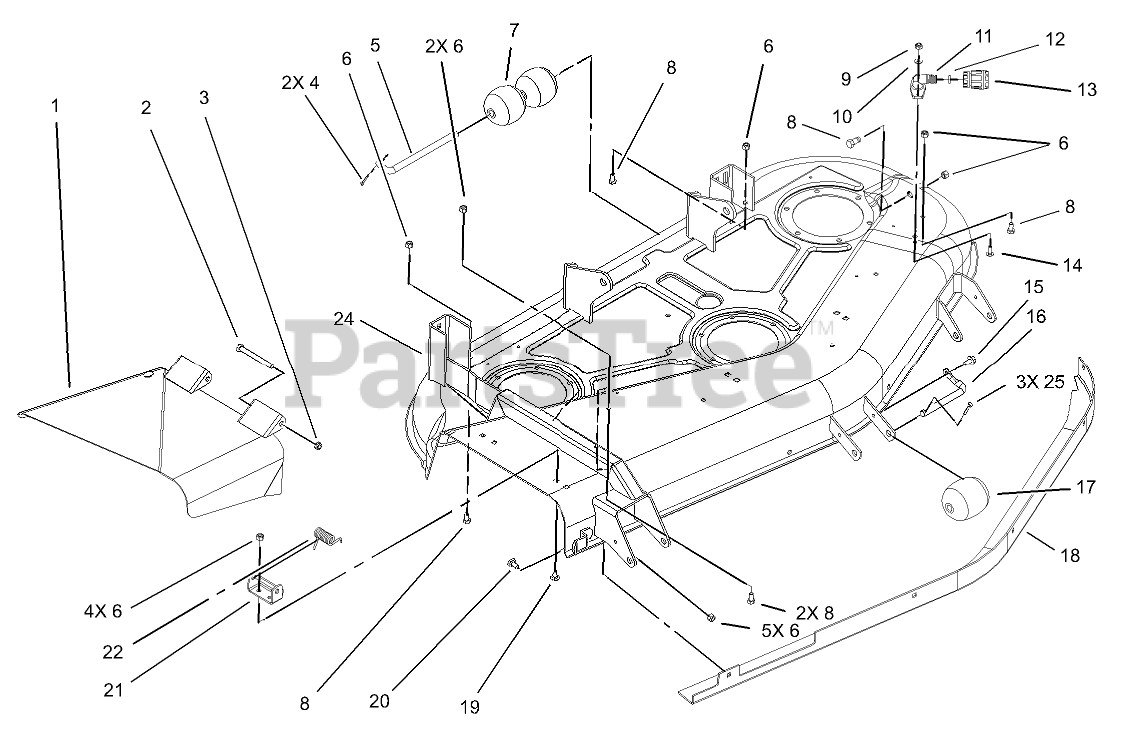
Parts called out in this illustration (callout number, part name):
1	Deflector ASM
1:1	DECAL-DANGER
1:2	DECAL-DANGER
2	SCREW-HH
3	NUT-HEX
4	PIN-COTTER
5	SHAFT-ROLLER, REAR
6	NUT-LOCK, NI
7	ROLLER
8	SCREW-HH
15	SCREW-HWHTF
16	Shaft-Roller
17	ROLLER
18	BAFFLE
19	SCREW-CARR
20	BOLT-CARR
21	BRACKET-PIVOT
22	SPRING
24	52IN DECK/DECAL ASM
24:2	DECAL-CAUTION
24:3	DECAL-DANGER
24:4	NUT-LOCK, NI
24:5	WASHER-FLAT
24:6	FITTING-WASHOUT
24:7	O-RING
24:8	BOLT-CARR
24:9	CONNECTOR-HOSE
25	PIN-COTTER
